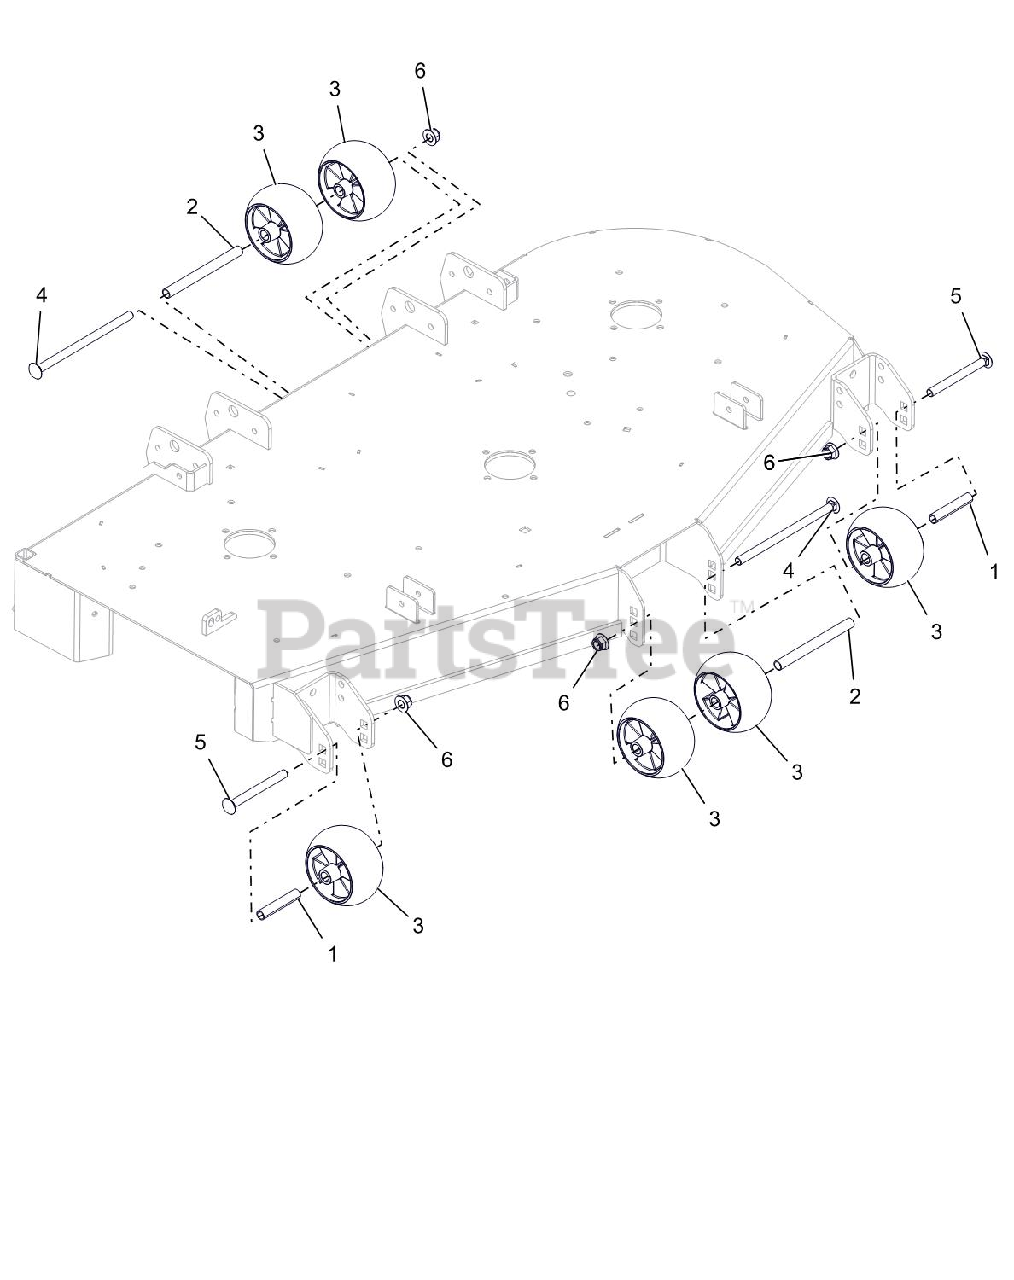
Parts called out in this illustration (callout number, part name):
1	.510X.625X3.35 SPACER-LOW FILM
2	.510X.625X6.50 SPACER-LOW FILM
3	ANTI-SCALP WHEEL - 5X3 CTR
4	@BLT-RDHDSQNK .50-13X8.50 G5YZ
5	BLT-RDHDSQNK .50-13X5.00 GR5YZ
6	@NUT-LK-NYL-FLG .50-13 YWZC
